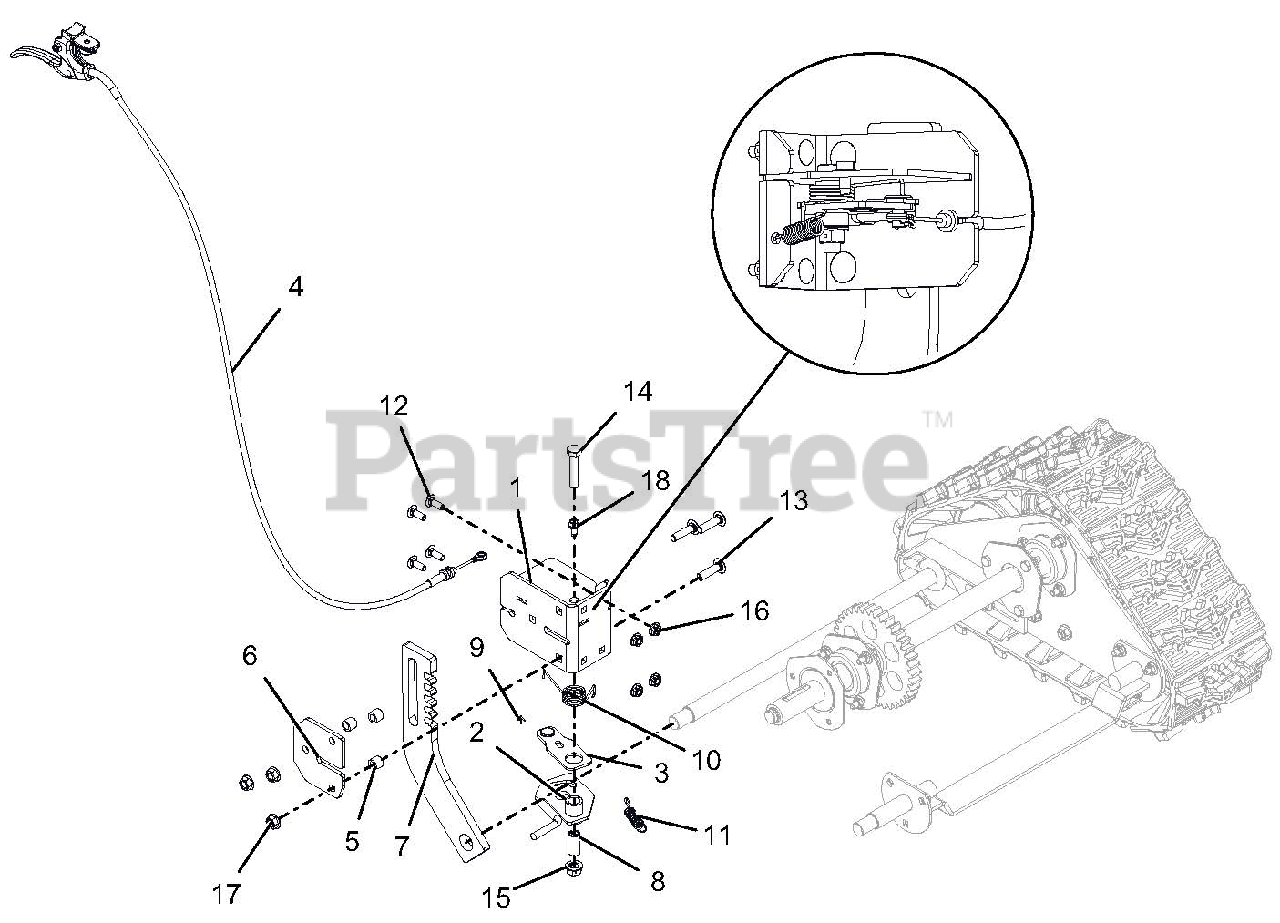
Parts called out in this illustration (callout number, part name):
1	BRACKET, HEIGHT ADJUSTER
2	LOCK, HEIGHT ADJUSTER
3	ARM, OVERTRAVEL
4	CABLE, TRACK REMOTE
5	SPACER .50 X .32 X .42
6	PLATE, HEIGHT ADJUSTER
7	STOP, HEIGHT ADJUSTER-CPT BLAC
8	BSHG-SLV .385X.500X1.045
9	PIN-HAIR INT .06X.18X.77
10	SG-TORS .067X.88
11	SPRING-EXT .047 X .438 X 1.85
12	@BLT-RDHDSQNK .25-20X.75 G5YZ
13	@BLT-RHDSHSQNK.31-18X1.25 G5YZ
14	@BLT-HEX .38-16X1.75 GR5 YWZC
15	NUT-LK-CTR-FLG .38-16 YWZC
16	@NUT-LK-CTR-FLG .25-20 YWZC
17	@NUT-LK-TOP-FLG .31-18 YWZC
18	SCR-TAP .25-20X.50 HWH TR YWZ
